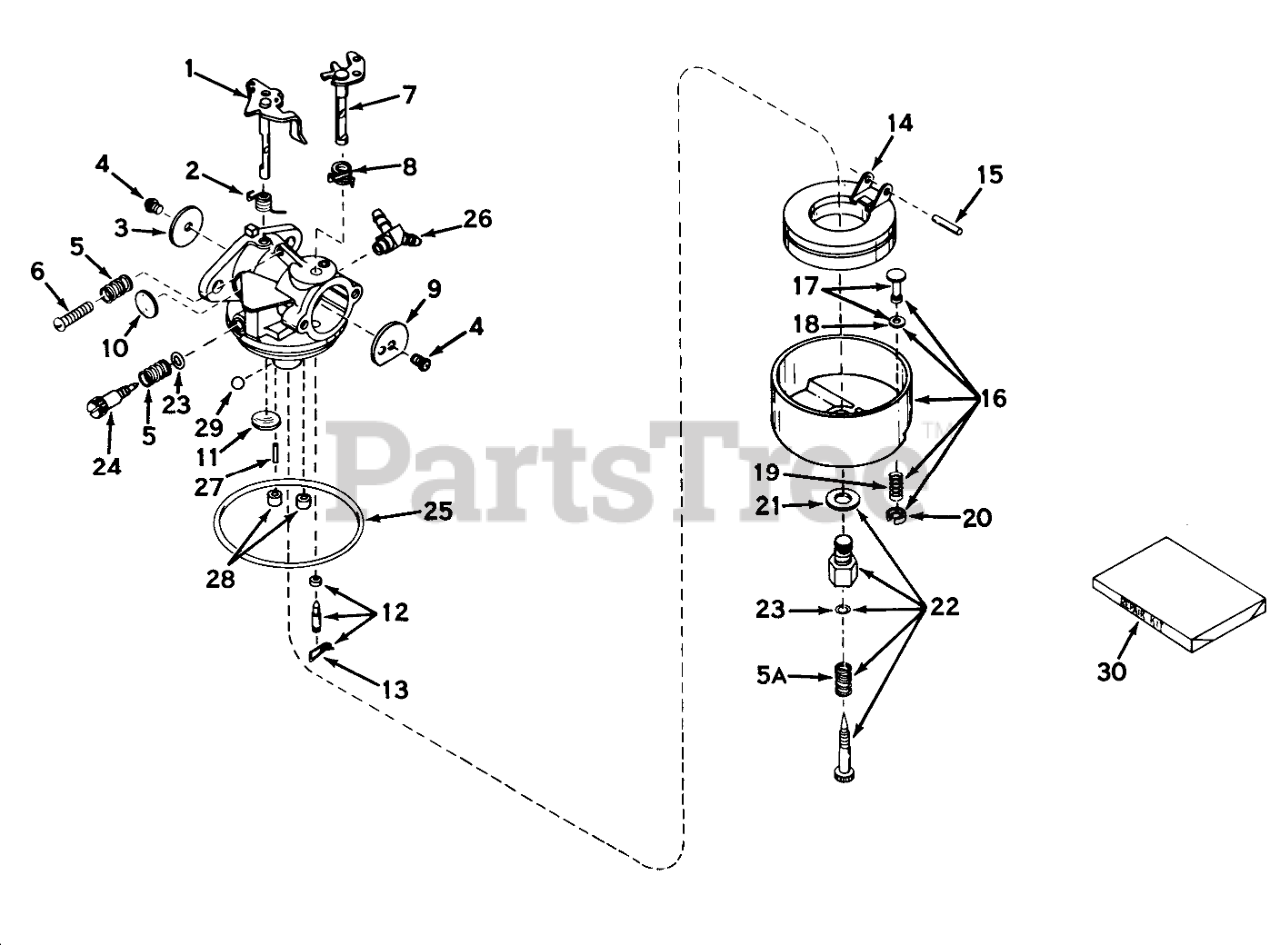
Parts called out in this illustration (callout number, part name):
1	Shaft/Lever-Throttle
2	Spring, Return
3	Shutter-Throttle
4	Screw-Shutter
5	Spring-Tension
6	Screw-Throttle Crack Screw / Idle Speed
7	Shaft& Lever Assy., Choke
8	Spring, Choke return
9	Shutter-Choke
10	Plug-Welch, Idle Mixture Well
11	Plug-Welch, Atmospheric Vent
12	Inlet Needle, Seat & Clip Assy. (Incl. No. 13)
13	Clip-Spring
14	Float,Carburetor
15	Shaft-Float
16	Bowl & Drain Assy., Float (Incl. Nos. 17 thru 20)
17	Plunger Assy., Drain (Incl. No. 18)
18	Gasket-Plunger, Drain
19	Spring, Drain Plunger
20	Retainer, Plunger Spring
21	Washer-Bowl Nut
22	Adjustment Screw Assy., Main (Incl. Nos. 5A, 21 & 23)
23	"O"Ring
24	Screw, Idle Adj.
25	O Ring-Bowl, Float
26	Fitting, Fuel inlet
28	Plug, Cup
29	BalI, Steel
30	Repair Kit
